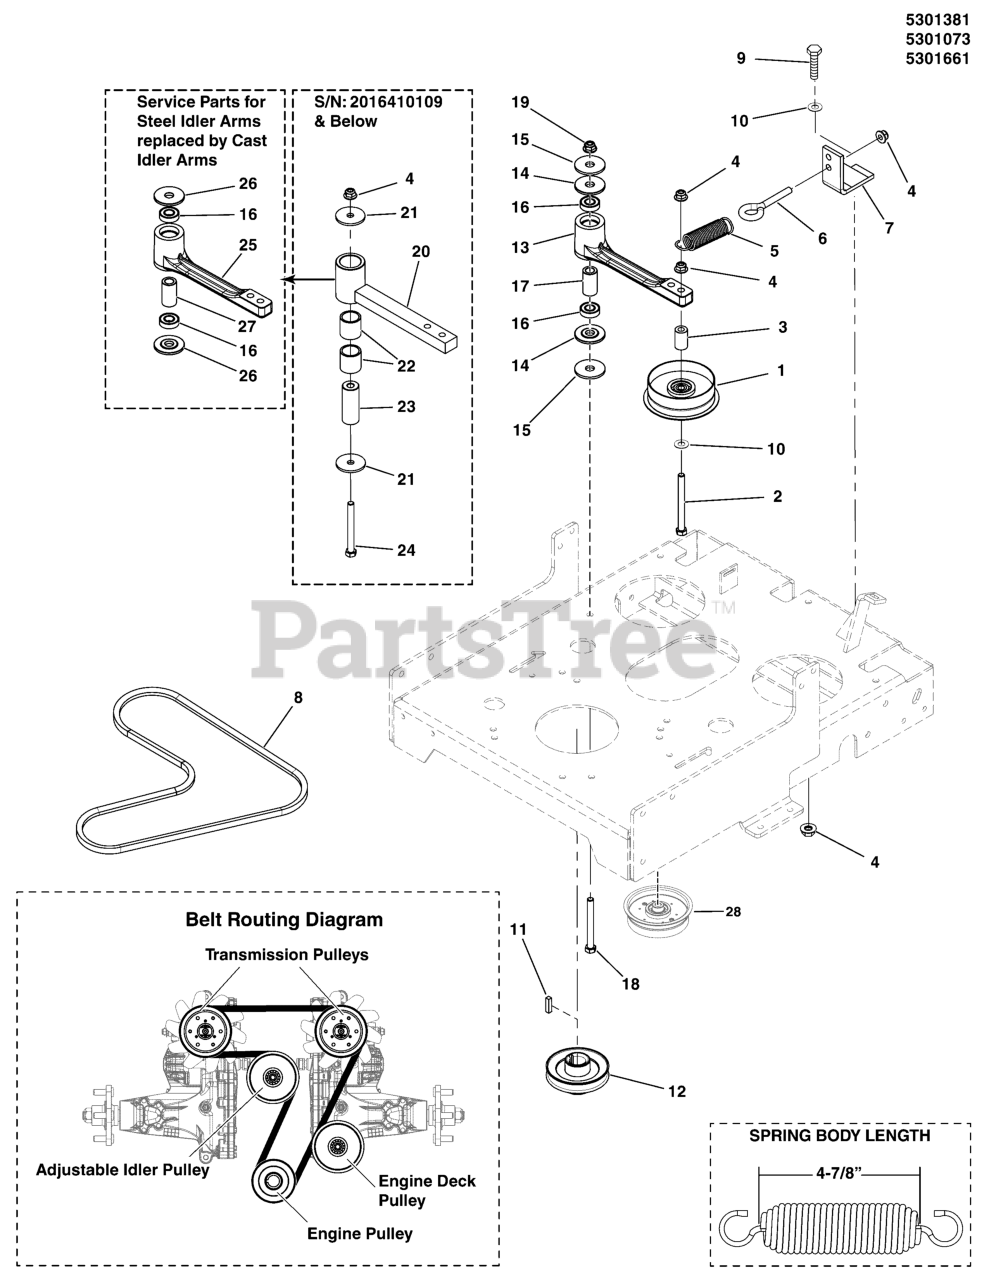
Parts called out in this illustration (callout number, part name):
1	PULLEY, SINGLE FLANGED, 4"ODX3/8"ID
2	BOLT, 3/8-16 X 4" GD5 CZ
3	SPACER, .38 X .75 X 1.25, CZ
4	NUT, 3/8-16 HEX NYLOCK FLANGE
5	SPRING-EXT, 1.25 ODX5.70LGX.142WR, BLK
6	EYE BOLT, 3/8-16 X 5, 2.88THRD, 1EYE, CZ
7	BRACKET, EYEBOLT - RED
8	BELT, A-SEC, 61.38EL, ARAMID, WRPD
9	BOLT, 3/8-16 X 1" GD5 CZ
10	WASHER, 3/8 SAE
11	KEY, 1/4 SQ X 1
12	PULLEY, CRANKSHAFT, 1.0005 ID X 4.25 OD
13	ASSM, IDLER ARM, PUMP DRIVE, 1/2IC, CAST
14	SPACER, IDLER ARM, 1/2, PM
15	WASHER, .52 X 1.75 X .14, CZ
16	BEARING, BALL, AXLE
17	SPACER, .52 X .84 X 1.53, PM
18	BOLT, 1/2-13 X 3-1/2, HEX HD, GD5, CZ (SV)
19	NUT, Hex Flange, Nylock, 1/2-13
21	WASHER, .41 X 1.75 X .14
22	BUSHING, BRASS, 1.25X1X1.25
23	SPACER, .39 X 1.00 X 2.55, SS
24	BOLT, 3/8-16 X 3-1/2" GD5 CZ
25	ASSM, IDLER ARM, PUMP DRIVE, 3/8ID, CAST
26	SPACER, IDLER ARM, T-STYLE, CZ
27	SPACER, .39 X .88 X 1.53, CZ
28	SEE ENGINE & PTO GROUP
